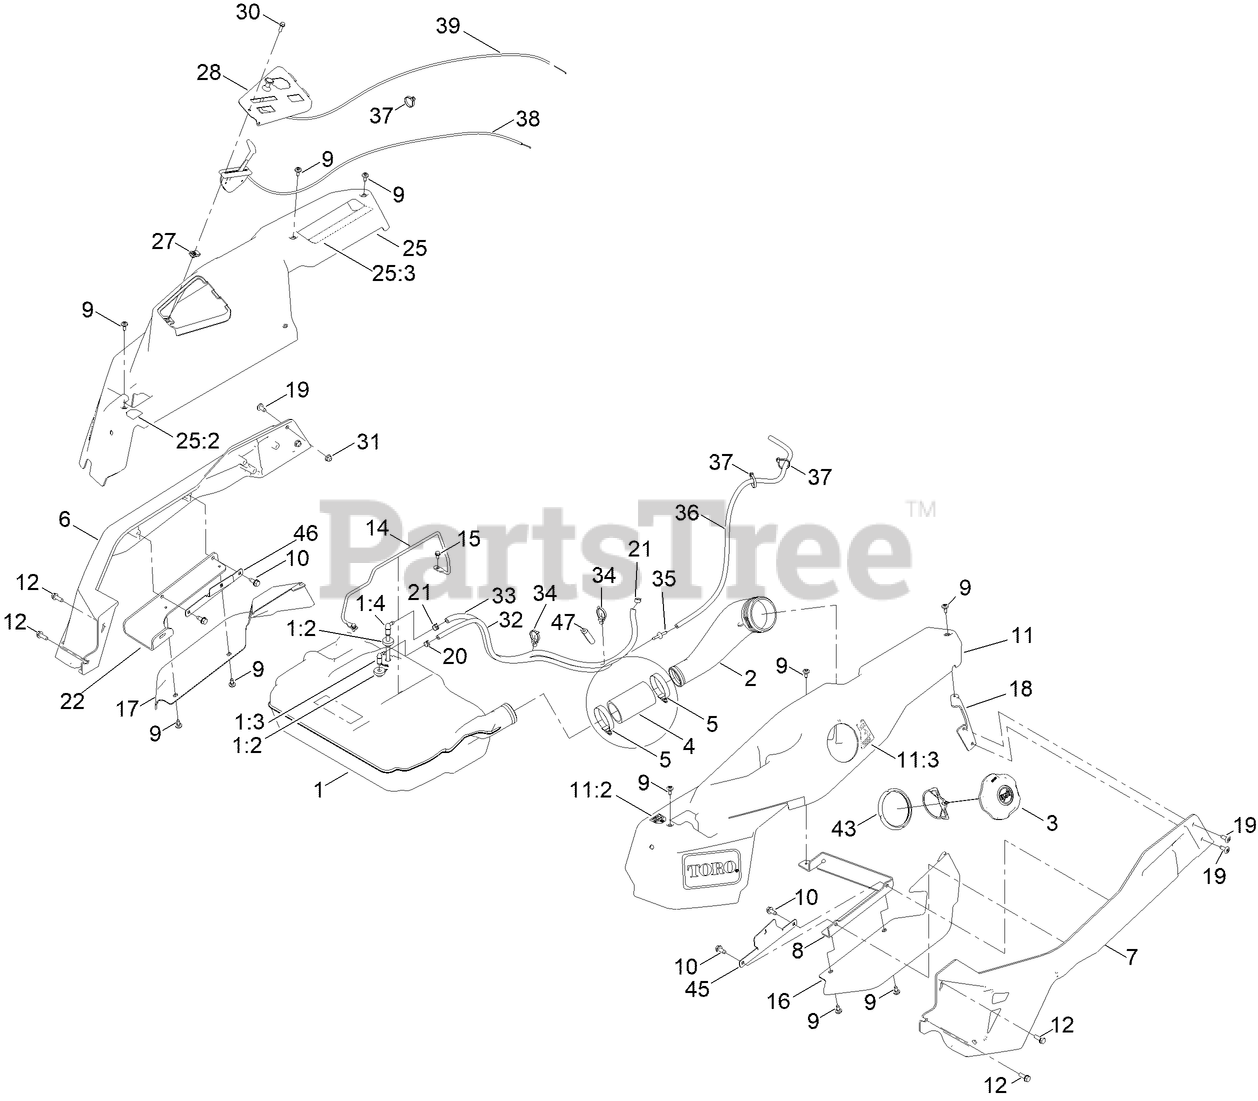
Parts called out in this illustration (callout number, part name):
1	TANK-FUEL ASM
1:2	BUSHING
1:3	FITTING-ELBOW 90
1:4	FITTING - PICKUP, FUEL
2	NECK-FILLER, FUEL
3	CAP-FUEL, RATCHETING
4	HOSE-FILLER, FUEL
5	CLAMP-HOSE
6	CAST-TUBE, RH [BLK-TXT]
7	CAST-TUBE, LH [BLK-TXT]
8	MOUNT-POD BRACKET LH
9	SCREW-SHOULDER
10	SCREW-HWHTF
11	POD ASM - LH W/DECALS
11:2	DECAL-CONTROL LEVER, LH
11:3	DECAL-FUEL FILL
12	SCREW-TAPTITE
14	ROD-HOLD DOWN
15	SCREW-HWH
16	FENDER-TIME CUTTER, LH
17	FENDER-TIME CUTTER, RH
18	BRACKET-REAR POD, LH
20	CLAMP-HOSE
21	CLAMP-HOSE
22	BRACKET-MR SPRING
25	POD ASM - RH , MR W/DECALS
25:2	DECAL-CONTROL LEVER, RH
25:3	DECAL - MYRIDE
28	PANEL-CONTROL
30	SCREW-HWH
31	NUT-HF
32	HOSE-FUEL
33	HOSE-FUEL
34	CLIP-TIE
35	ADAPTER ORIFICE
36	HOSE-LP
37	TIE-CABLE
38	CABLE-THROTTLE
39	CABLE-CHOKE
43	RING-RETAINING
45	BRACKET-ALIGNMENT, POD LH
46	BRACKET- ALIGNMENT, POD RH MR
